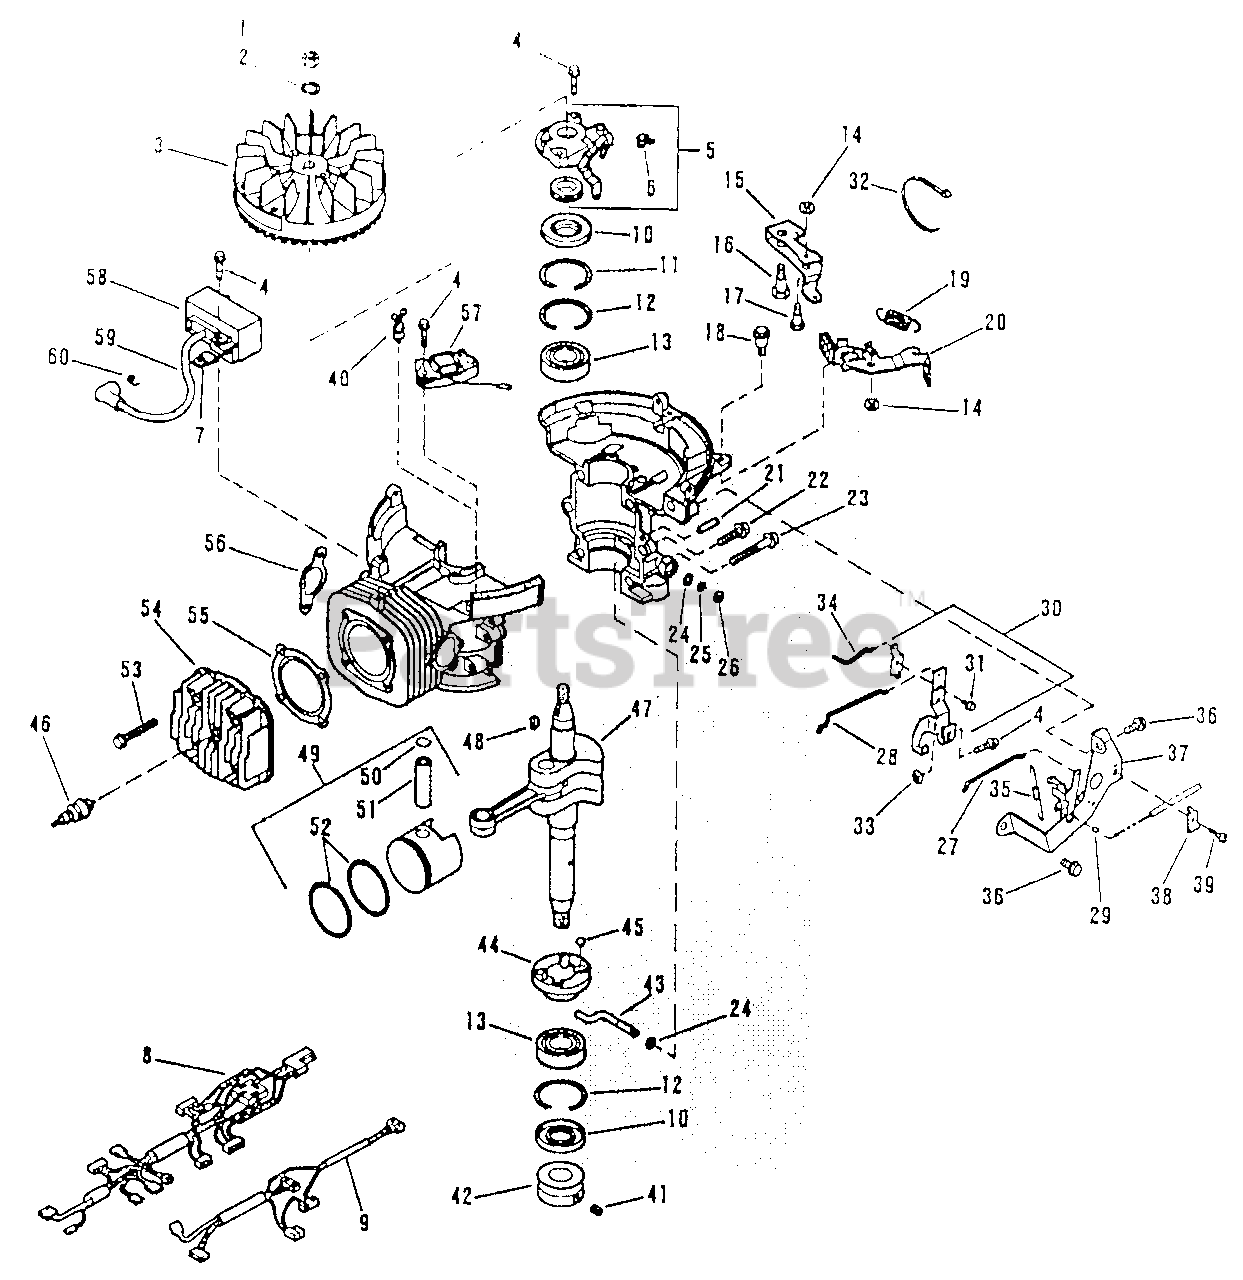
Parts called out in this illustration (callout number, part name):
1	Nut-Flywheel
2	Lockwasher
3	Flywheel
4	Screw
5	Oil Pump Kit w/Oil Lines
6	Clamp-Oil Line
7	Terminal-C.D. Ignition Module
9	Wire Harness
10	Oil Seal-Crankshaft
11	Retaining Ring
12	Retaining Ring
13	Bearing-Crankshaft
16	Shoulder Bolt
21	Taper Pin
22	Screw
23	Screw
24	Washer-Governor Shaft
25	Retainer Ring-Governor Shaft
26	Oil Seal-Governor Shaft
27	Choke Rod
28	Throttle Rod
29	Throttle Wire Retainer
30	Governor and Oil Pump Lever Kit
31	Screw
32	Tie Strap
33	Nut
34	Oil Pump Control Rod
35	Governor Spring
36	Screw
37	Bracket and Switch Assembly
38	Clamp-Throttle Cable to Bracket
39	Screw
40	Wire Tie
41	Set Screw-Engine Pulley
42	Engine Pulley
43	Governor Shaft
44	Governor Ramp
45	Ball-Governor
46	Spark Plug
47	Crankshaft and Connecting Rod (BMRB, C & D)
48	Key-Crankshaft (BMRB, C & D)
49	Piston and Ring Assy. (Standard)
50	Retaining Ring
51	Wrist Pin
52	Ring Set (Standard)
52	Ring Set (0.020" Oversize)
53	Screw-Cylinder Head to Block
54	Cylinder Head
55	Head Gasket
56	Exhaust Gasket
58	C.D. Ignition Module
59	High Tension Lead and Cover
60	Spring Terminal
